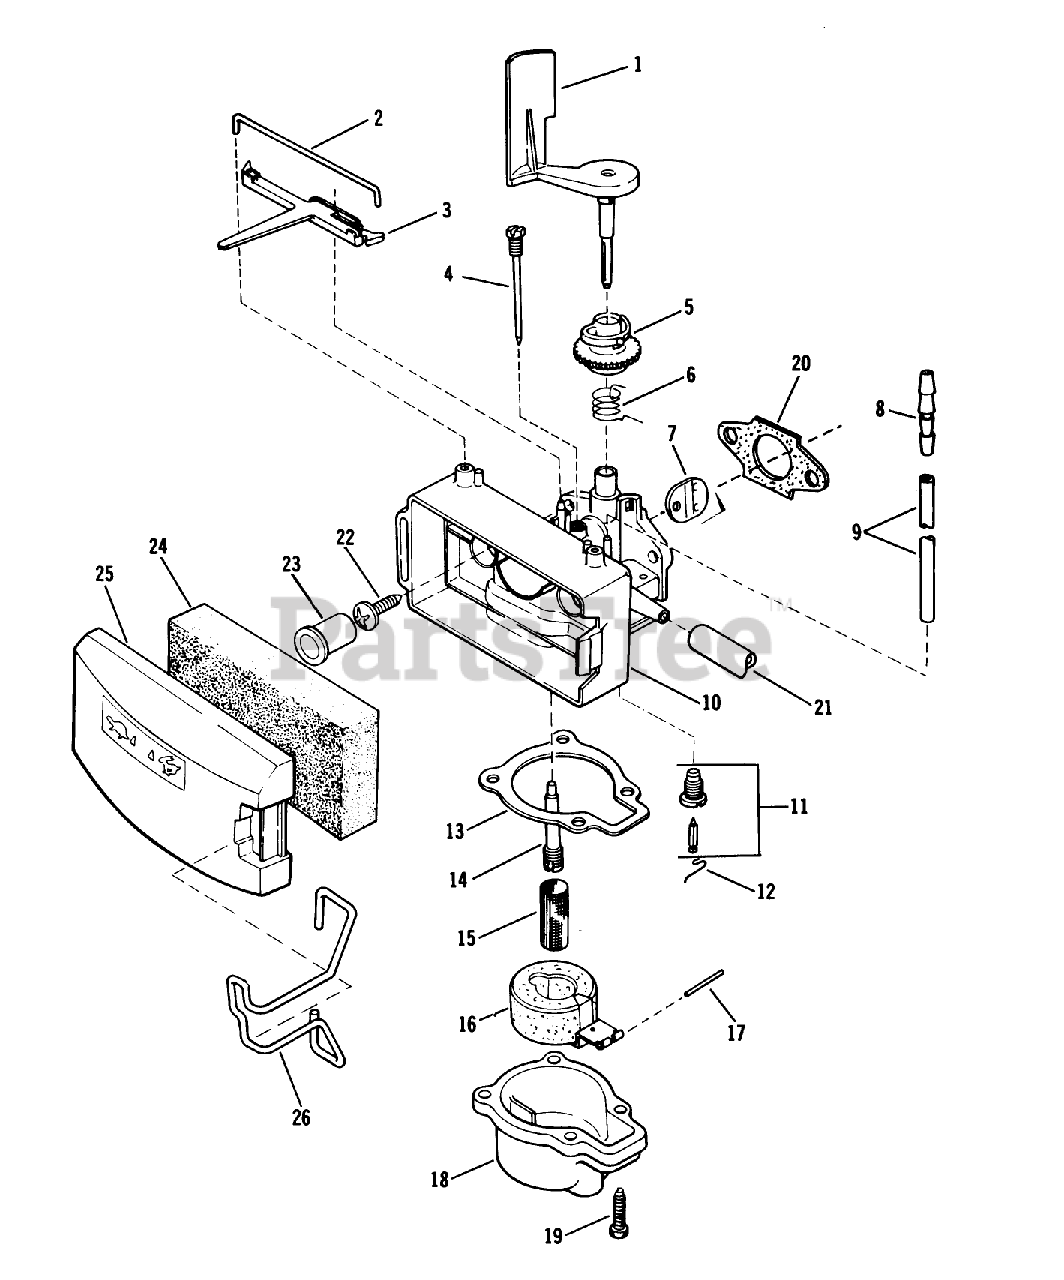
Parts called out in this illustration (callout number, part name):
2	RETAINER
3	LEVER S
4	NEEDLE ADJ. AY S
5	COLLAR-ADJUST, AIRVANE
6	SPRING,THROTTLE S
7	DISC S
8	REDUCER-CONNECTOR
9	TUBING S
10	CARB BODY S
15	FILTER-FUEL VS
19	SCREW-HH
20	GASKET CARB S
21	GAS LINE
22	SCREW
26	RETAINER-COVER, FILTER
